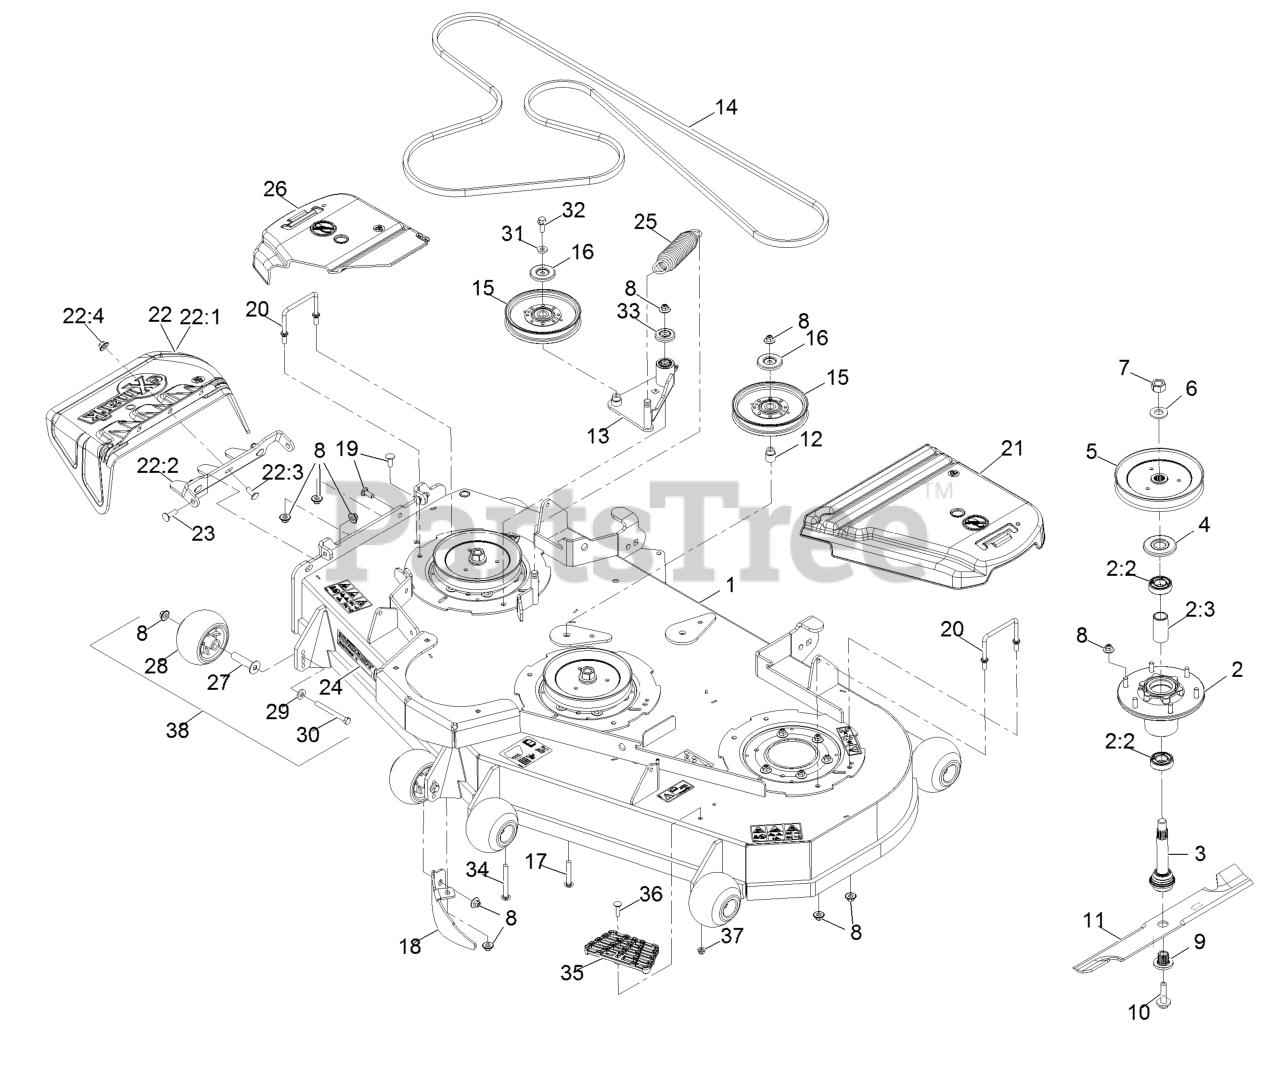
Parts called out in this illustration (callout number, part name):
1	Deck ASM, W/Decals 60
2	ASM-Cutter Hsg With Bearings
2:2	Bearing-Ball
2:3	Spacer-Bearing
3	ASM-Spindle And Seal
4	Guard,Bearing Top .989
5	Sheave,Blade Drive 7.25
6	Washer-Spring Disc 3/4
7	Nut-Hex
8	Nut-Nyloc 3/8-16 Flg
9	Bushing, Splined
10	Screw-Sems 1/2-20 X 2.19
11	Blade-Extreme 2, 20.50"
11	Blade, Notched
11	Blade, Mulching
11	Blade, Low Lift
11	Blade, Solid
12	Bushing, Idler
13	Idler Arm ASM
14	Belt-V, B
15	Idler-Pulley
16	Shield-Dust
17	Bolt-Carriage 3/8-16 X 2 1/2
18	Dogleg - Lz60
19	Bolt-Carriage 3/8-16 X 1
20	Wireform-Cover
21	Cover-Belt, LH
22	ASM,Discharge Chute
22:1	Chute, Discharge
22:2	Bracket,Discharge Chute
22:3	Bolt-Carriage 3/8-16 X 1
22:4	Nut-Nyloc 3/8-16 Flg
23	Bolt-Carriage 3/8-16 X 1 1/
24	Decal, 604
25	Spring-Extension
26	Beltshield-Rt, 60
27	Axle, Roller
28	Roller-Anti-Scalp
29	Washer-Spring Disc 3/8
30	Screw-HH 3/8-16 X 3 3/4 GR 8
32	Screw-HH Flg 3/8-16 X 1
33	Guard-Top
34	Bolt-Carriage Shoulder 3/8-16 X 3 1/2
35	Step-Deck
36	Bolt-Carriage 5/16-18 X 1 1/4
37	Nut-Nyloc 5/16-18 Flg
38	Kit, Anti-Scalp Roller
